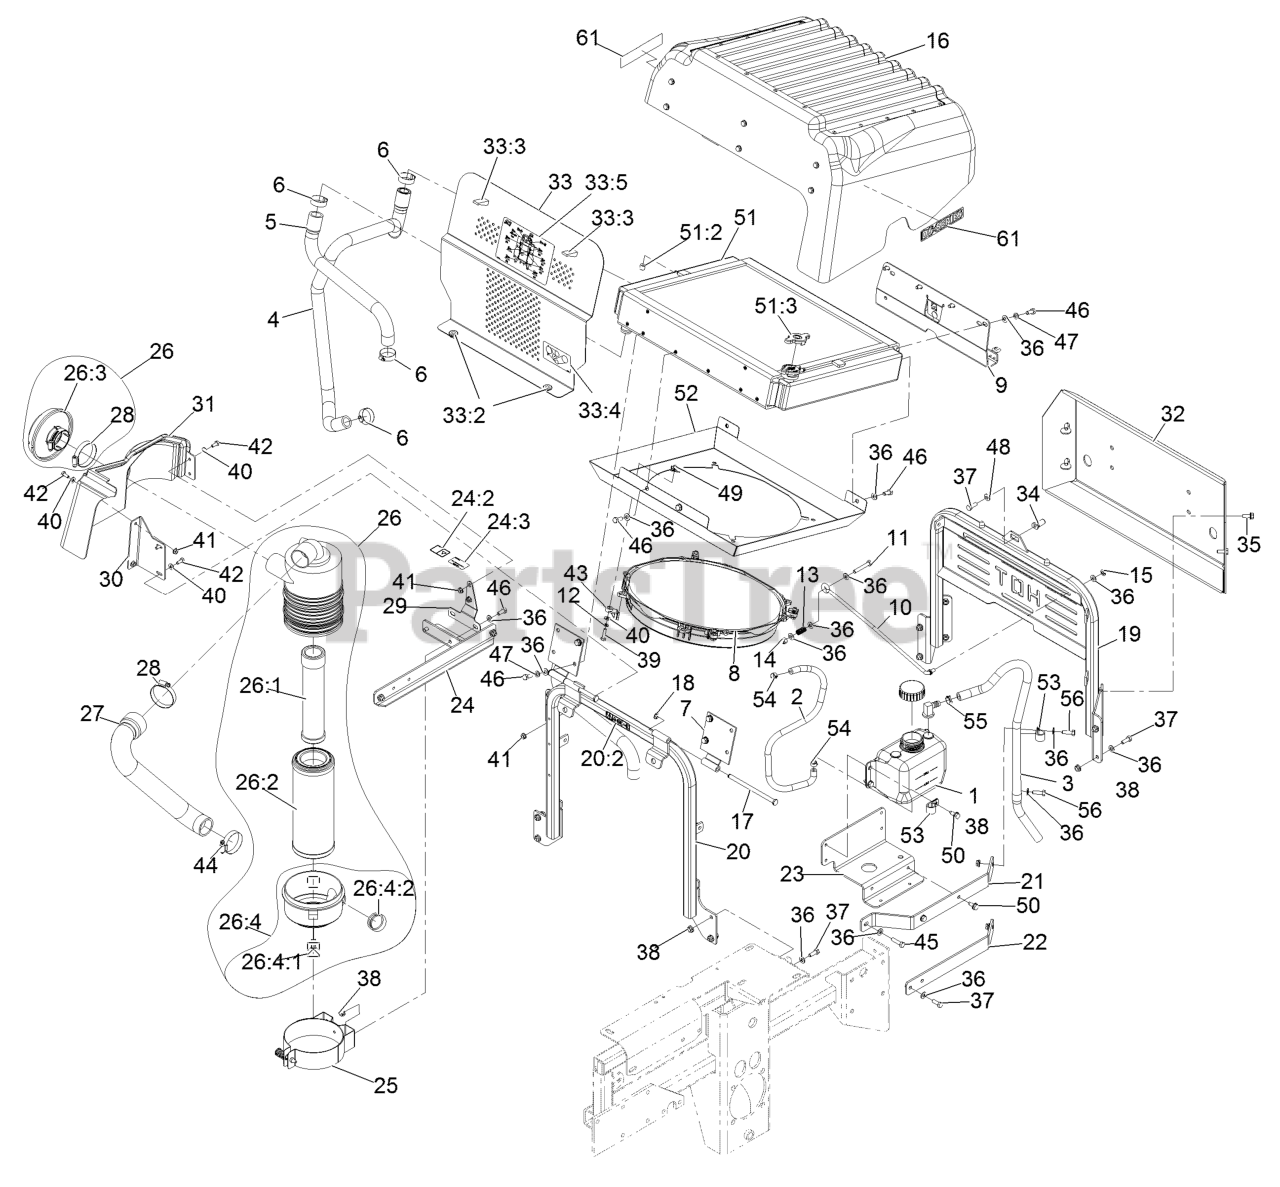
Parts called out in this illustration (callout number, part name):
1	TANK, OVERFLOW W/CAP
2	HOSE, .313 I.D.X 25.0 REI
3	HOSE, .500 I.D. X 30" EPD
4	HOSE,RADIATOR LOWER D902
5	HOSE,RADIATOR UPPER D902(
6	CLAMP-HOSE
7	WLD,HINGE PLATE
8	FAN- ELECTRIC
9	ASM-LATCH PLATE
10	ROD,PROP
11	SCREW-HH
12	SCREW-HH
13	SPRING,LOCK PIN
14	NUT-LOCK, NI
16	HOOD ASM, D902
19	WLD,REAR GUARD
20	ASM, RAD. MOUNT W/ DECALS
20:2	DECAL-DANGER
22	RIB, BOTTOM
23	BRACKET, BOTTLE-HYDRO TAN
24	Wld, Air Cleaner Mount
24	ASM,AIR CLNR BRKT W/DECAL
24:2	DECAL-WARNING
24:3	DECAL-CAUTION
25	BRACKET-FILTER, AIR
26	FILTER-AIR
26:1	FILTER-AIR, SAFETY
26:2	FILTER-AIR
26:3	HOOD-CLEANER, 2" AIR INTA
26:4	COVER-FILTER, AIR
26:4:1	CLIP-CLEANER, AIR
26:4:2	EJECTOR, NELSON AIR CLEAN
27	HOSE,AIR INTAKE D902(8015
28	CLAMP-HOSE
29	BRACKET,REAR COVER
30	BRACKET,FRONT COVER
31	PANEL, SIDE
32	WLD,REAR BUMPER
33	ASM,PANEL W/ DECALS LXS L
33:2	GROMMET
33:3	LATCH-SWELL
33:4	DECAL-BELT PUMP ROUTING
33:5	Decal-Service Aid
34	PIN,LATCH
35	SCREW-HHF
36	WASHER-PLAIN
37	SCREW-HH
39	SCREW-HH
40	WASHER-FLAT
42	SCREW-HH
43	MOUNT,FAN
44	CLAMP-HOSE
45	SCREW-HH
46	SCREW-HH
47	WASHER-LOCK
48	WASHER-SPRING
49	Nut-Retainer-Panel 1/4-20
50	Screw-HWH 5/16-18 X 3/4 Tf
51	RADIATOR ASM, AL D902
51:2	PLUG-PIPE
51:3	CAP-RADIATOR
52	FAN SHROUD,16
53	CLIP-LOOM
54	CLAMP-HOSE
55	CLAMP-HOSE
56	SCREW-HH
61	DECAL, DS SERIES
